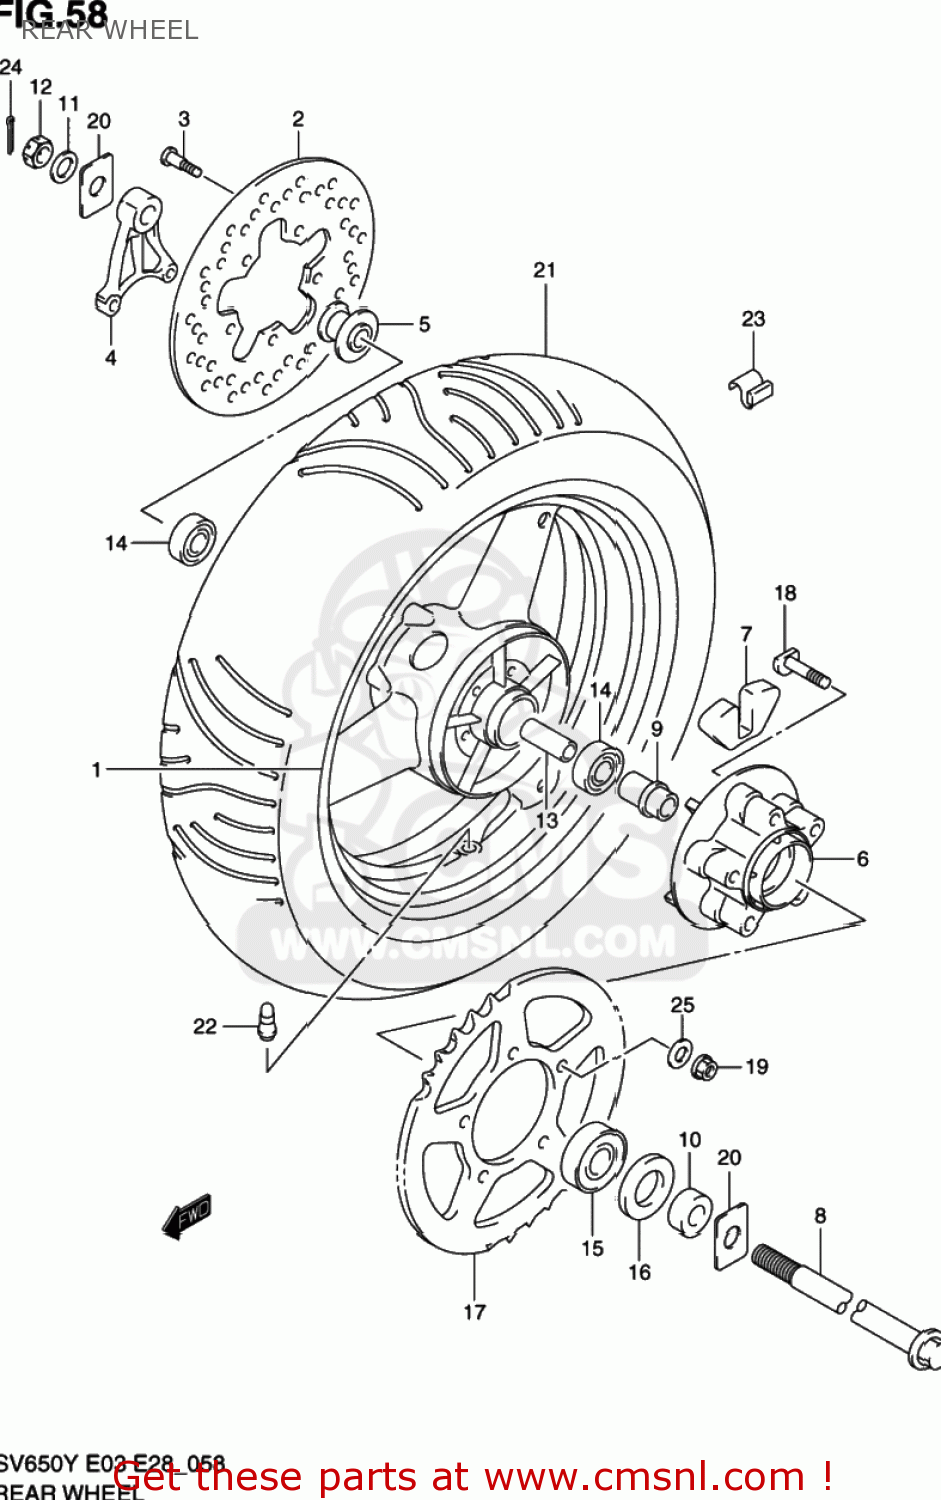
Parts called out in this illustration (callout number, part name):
1	WHEEL,REAR (17XMT4.50)
2	DISC,RR BRAKE
3	BOLT 8X33
4	BRACKET,RR CALIPER
5	SPACER,RR AXLE,R
6	DRUM,RR SPROCKET MOUNTING
7	ABSORBER,RR HUB SHOCK
8	AXLE,RR
9	RETAINER,RR SPROCKET DRUM
10	SPACER,RR AXLE,R
11	WASHER(17X30X3.2)
12	NUT
13	SPACER(17.5X25X88)
14	BEARING
15	BEARING(25X62X17)
16	SEAL,OIL(35X62X8)
17	SPROCKET,RR(NT:45-525)
18	BOLT(10X47)
19	NUT
20	WASHER,CHAIN ADJUSTER
21	TIRE 160/60 ZR17 (69W)
22	VALVE ASSY,WHEEL RIM(TR412)
23	BALANCER,WHEEL (10G)
24	PIN,COTTER
25	WASHER (10.5X22X2.3)
